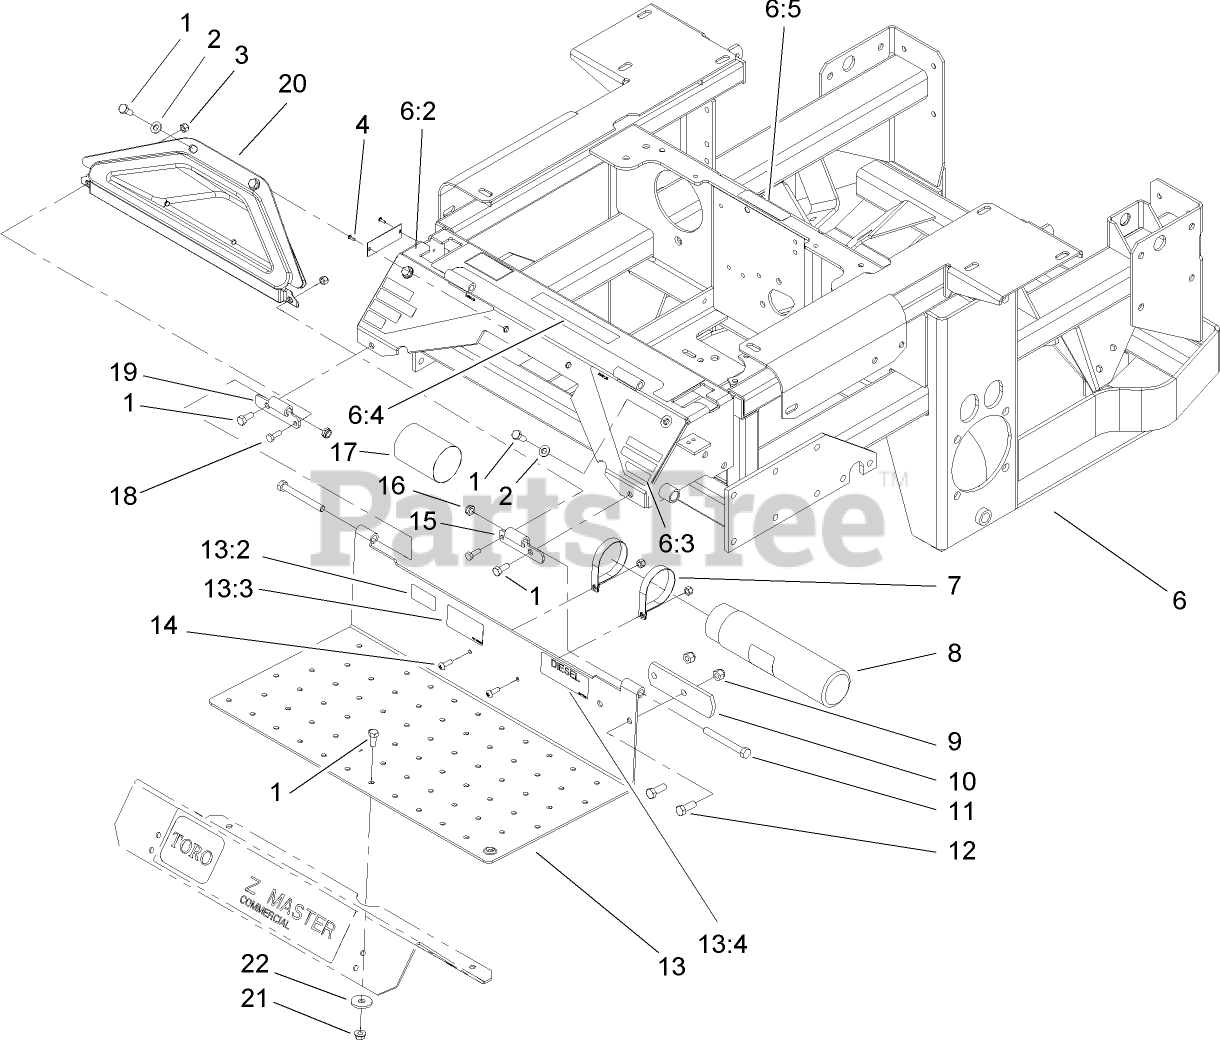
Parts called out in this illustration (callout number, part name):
1	SCREW-HH
2	WASHER-FLAT
3	NUT-LOCK, NI
4	RIVET
6	MAIN FRAME ASM
6:2	DECAL-DANGER, LEFT
6:3	DECAL-WARNING, RIGHT
6:4	DECAL-CONSOLE, TOP
6:5	DECAL-WARNING
7	R-Clamp
8	TUBE-MANUAL
9	NUT-LOCK, NI
10	STOP-BRAKE, PARK
11	SCREW-HH
12	SCREW-HH
13	FLOORPAN ASM
13:2	DECAL-PROTECTION, EAR
13:3	DECAL-LOCATION, MANUAL
13:4	DECAL-DIESEL
14	SCREW-PRH
15	Hinge-Floorpan, LH
16	NUT-LOCK, NI
17	CAP-HOUSING
18	SCREW-HH
19	Hinge-Floorpan, RH
20	Pocket
21	NUT-HF
22	WASHER
